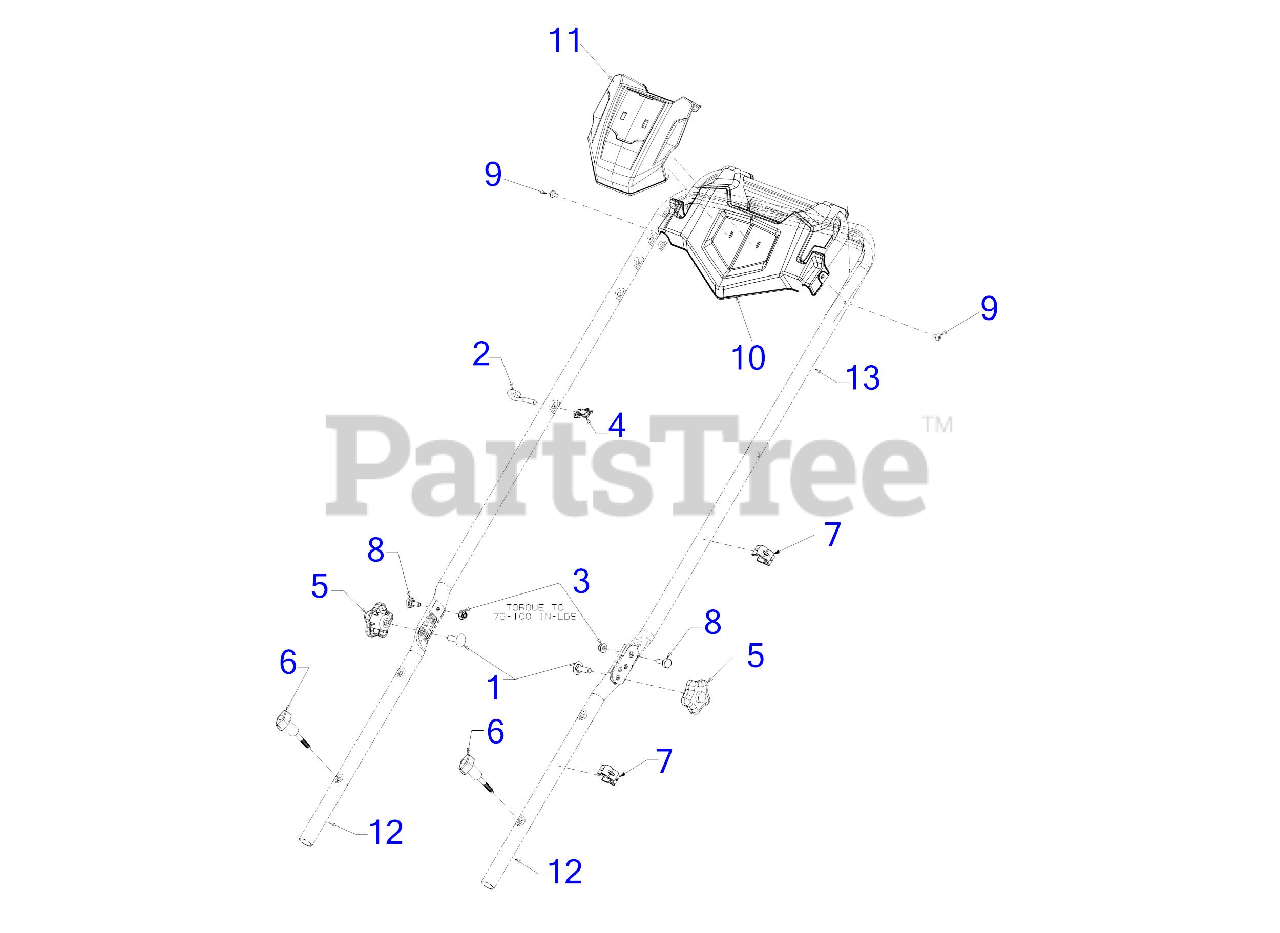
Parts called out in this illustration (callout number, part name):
1	SCREW 5/16-18 x 1.00 GR5
2	EYEBOLT 1/4-20
3	FLANGE LOCK NUT
4	HANDLE KNOB
5	STAR KNOB- YELLOW
6	WING KNOB 1/4-20
7	CONDUIT CLIP
8	SHOULDER SCREW
9	SCREW 1/4-14 x .625
10	HANDLE CONSOLE
11	CONSOLE TRIM PIECE
12	LOWER HANDLE
13	UPPER HANDLE
